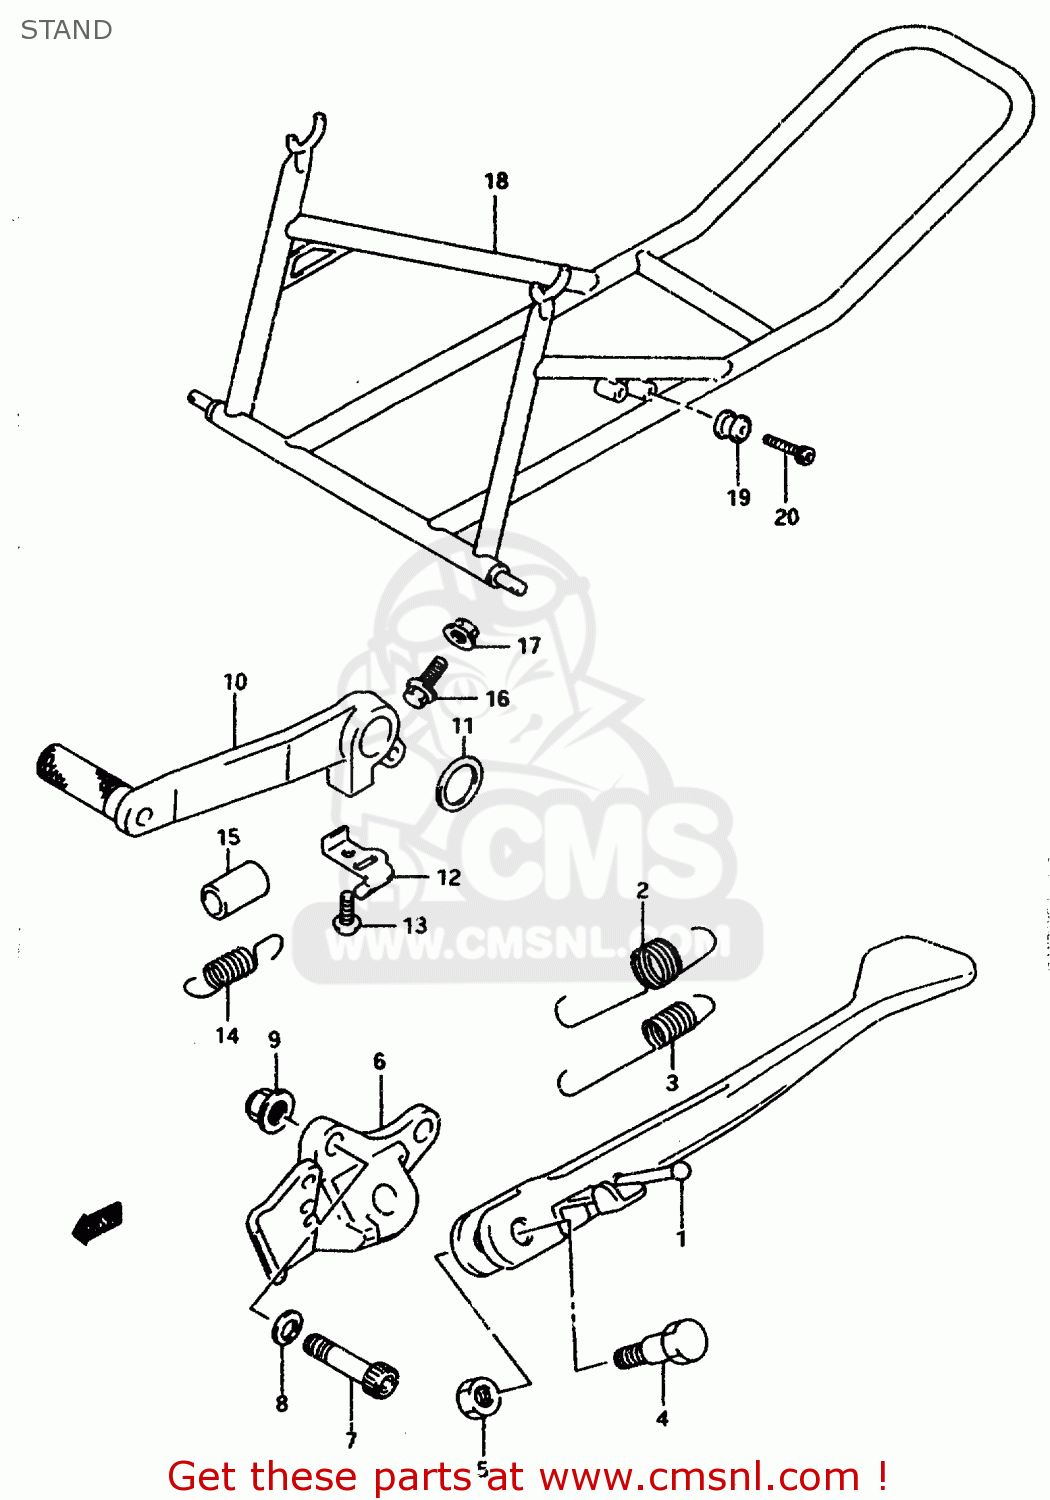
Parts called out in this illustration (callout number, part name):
1	STAND,PROP
2	SPRING
3	SPRING
4	BOLT(10X38)
5	NUT
6	BRACKET COMP,PROP STAND
7	BOLT 10X38
8	WASHER
9	NUT
10	PEDAL,BRAKE
11	WASHER(18X24X1)
12	HOOK,RETURN SPRING
13	SCREW(6X12)
14	SPRING
15	TUBE,BRAKE SPRING GUIDE
16	BOLT 5X20
17	NUT
18	STAND ASSEMBLY,REAR
19	HOLDER,STAND
20	BOLT
